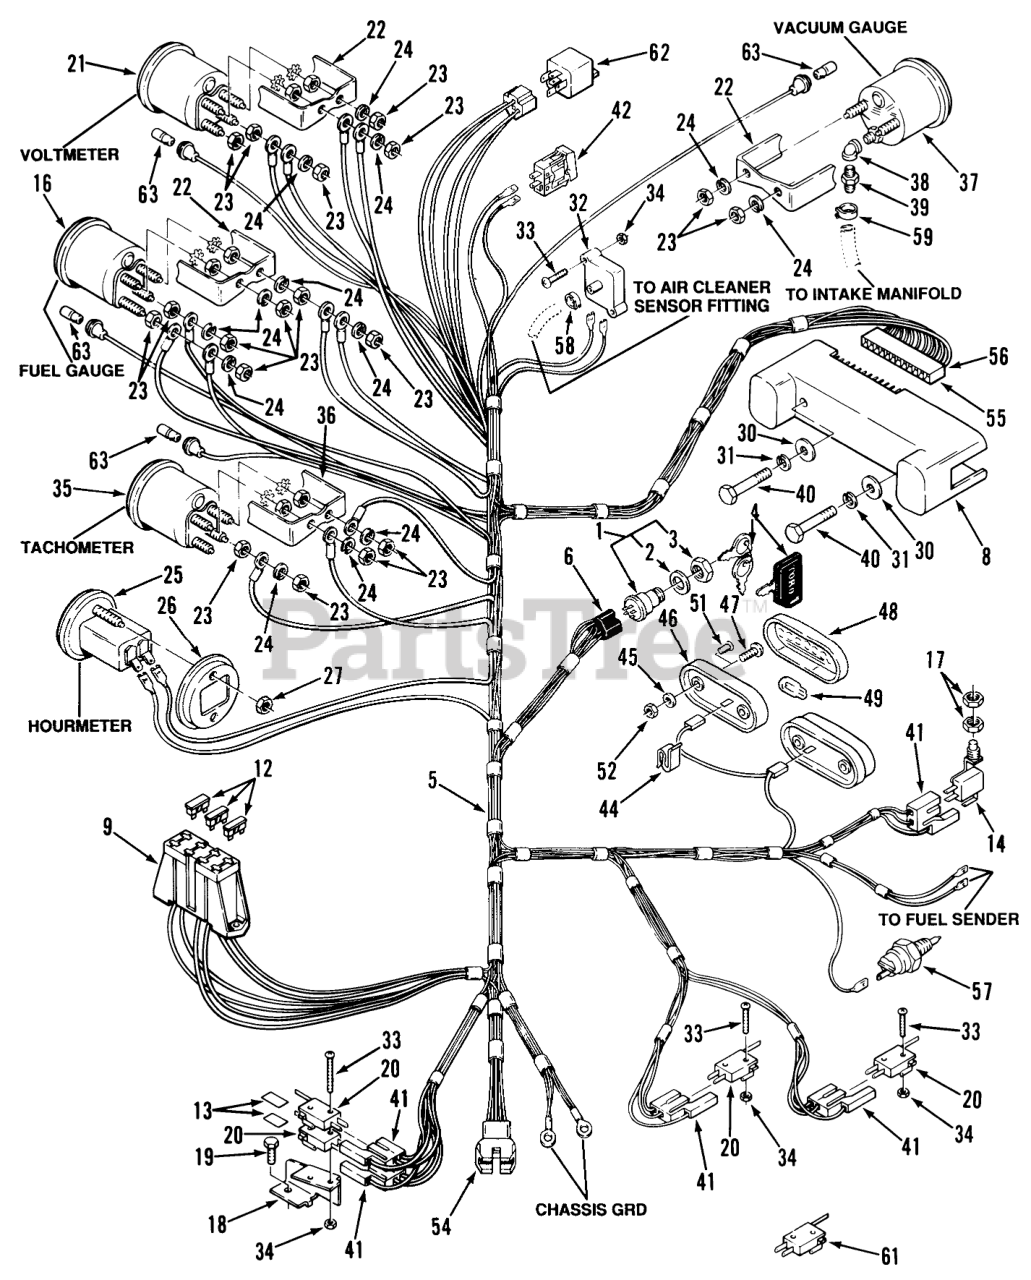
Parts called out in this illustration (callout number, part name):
1	IGNITION SWITCH ASM
2	Washer
4	Ignition Key
5	WIRING-HARNESS
6	CONNECTOR-5 WAY-SERV
8	CIRCUIT-BRD 8 LIGHT
9	FUSE-HOLDER 4 WAY
12	FUSE-10 AMP
13	BARRIER - SWITCH
14	Seat Switch
16	Fuel Gauge (Includes item 22)
17	NUT-HEX, SPECIAL
18	Support-Switch
19	Bolt
20	SWITCH
21	Voltmeter (Includes item 22)
22	BRKT-GAUGE MOUNTING
23	Nut
24	Lockwasher
25	Hourmeter (Includes item 26)
26	BRKT-GAUGE MOUNTING
27	Hex Nut
30	WASHER
31	LOCKWASHER
32	SENSOR-AIR CLEANER
33	Screw
34	NUT HEX 4-40 ELAST
35	Tachometer (Includes item 36) 520-H
36	MOUNTING-BRACKET
37	Vacuum Gauge (Includes item 22) 520-H
38	ELBOW
39	FITTING STRAIGHT
40	SCREW
40	ELBOW-45 DEG
41	CONNECTOR BODY
42	Light Switch
44	SPEED CLIP
45	Lockwasher
46	BASE-TAIL LIGHT
47	Screw
48	LENS-TAIL LIGHT
49	LIGHT BULB
51	RIVET-4
52	Nut
54	9-CIRCUIT CAP
55	Connector-Male
56	Terminal
57	SENSOR-HYDRO OIL HOT
58	CLAMP-HOSE 5/16"
59	Clamp
61	SWITCH - CLUTCH
62	RELAY
63	LAMP-MINIATURE GE 53X
